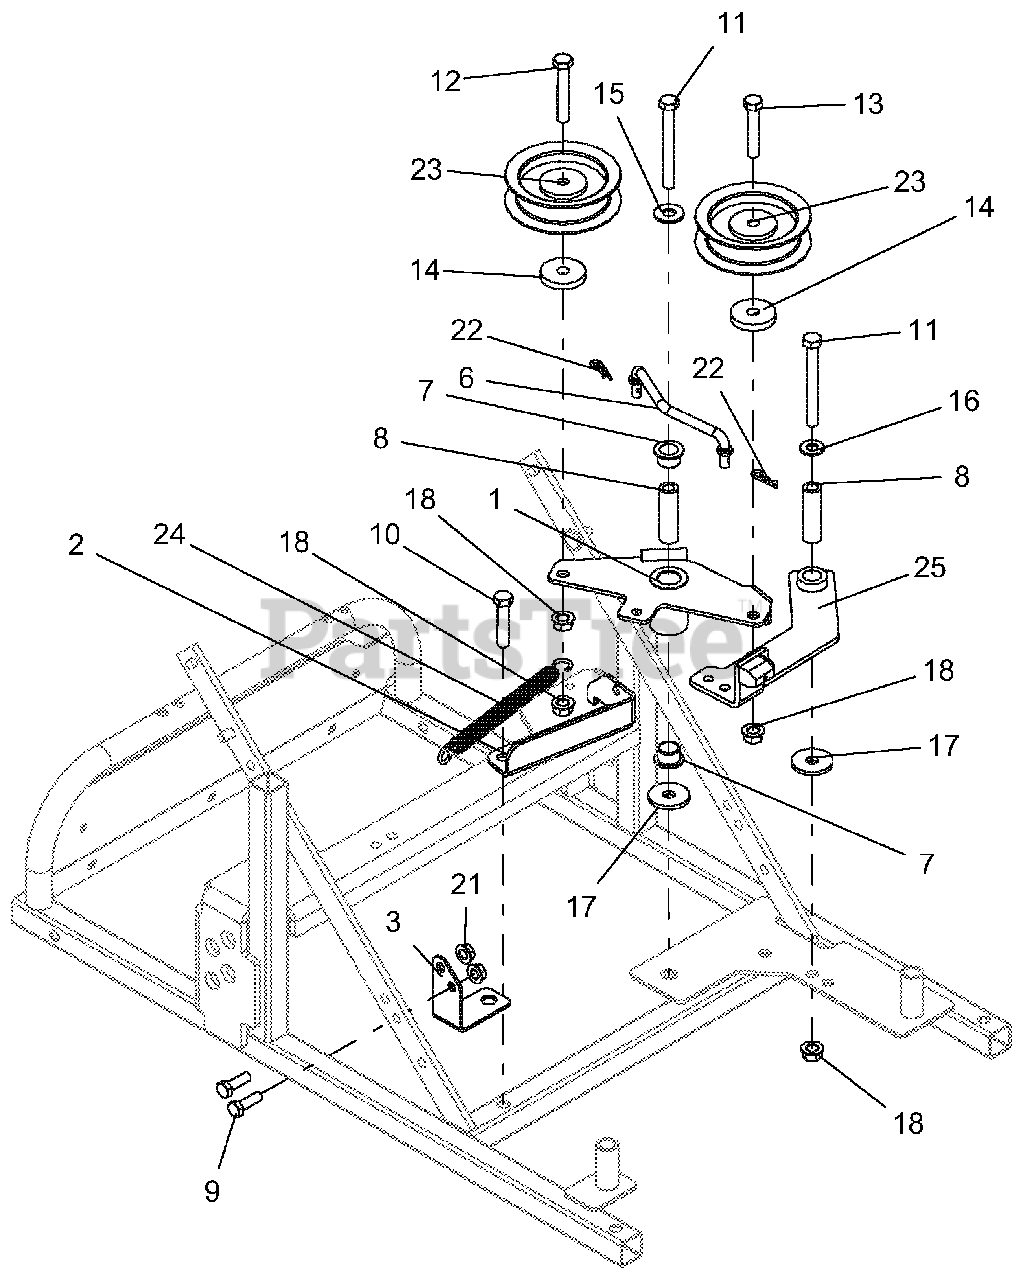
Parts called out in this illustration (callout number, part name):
1	WMT, IDLER ROCKER TM-26
2	MOUNT, LOWER PTO CABLE
3	MOUNT, HWM PTO IDLER SPRING
6	ROD, SPINDLE BRAKE
7	BSHG-FLG, .625X.750X.500X1.00
8	BSHG-SLV .375X.625X2.03
9	@BLT-HEX .31-18X1.00 GR5 YWZC
10	@BLT-HEX .38-16X1.75 GR5 YWZC
11	@BLT-HEX .38-16X3.25 GR5 YWZC
12	@BLT-HEX .38-16X2.25 GR5 YWZC
13	@BLT-HEX .38-16X2.00 GR5 YWZC
14	WSHR,FLT STL.406X1.50X.245YWZC
15	@WSHR-FL-STL.438X1.00X.083 YWZ
16	@WSHR-FL-STL.406X.812X.065 YWZ
17	WSHR-FL-STL .406X1.375X.135 YZ
18	@NUT-LK-TOP-FLG .38-16 YWZC
21	@NUT-LK-TOP-FLG .31-18 YWZC
22	PIN-HAIR INT .08X.18X1.18 YWZC
23	FLAT IDLER, STENS 280-671
24	SPRING, EXTENSION
25	KIT, BRAKE ARM ASSY, HWM
